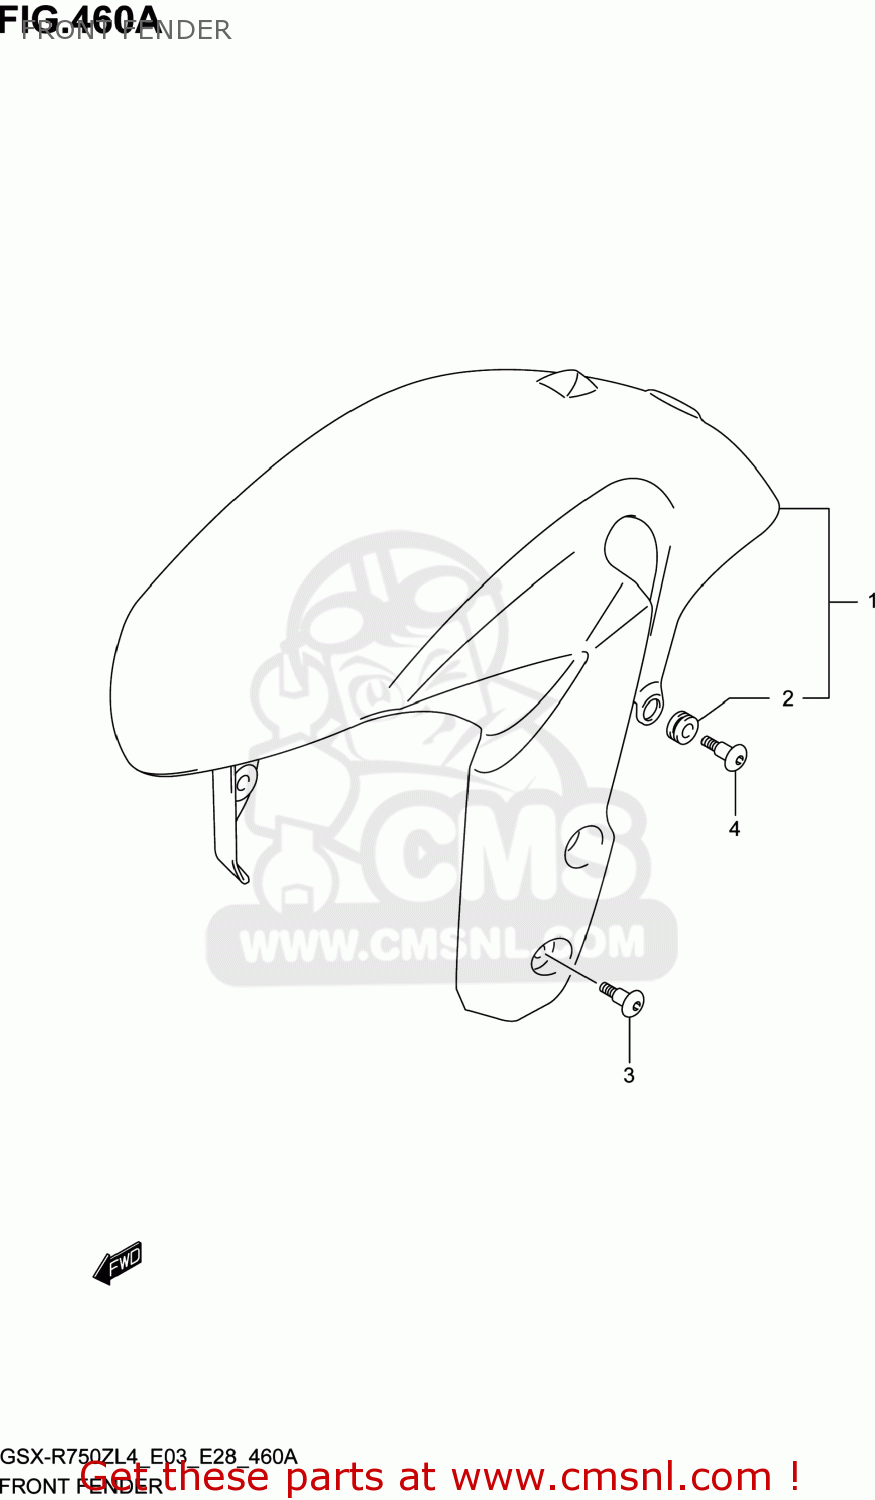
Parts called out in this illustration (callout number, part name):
1	FENDER ASSY,FRONT
2	CUSHION
3	SCREW(6X16)
4	SCREW(6X16)
